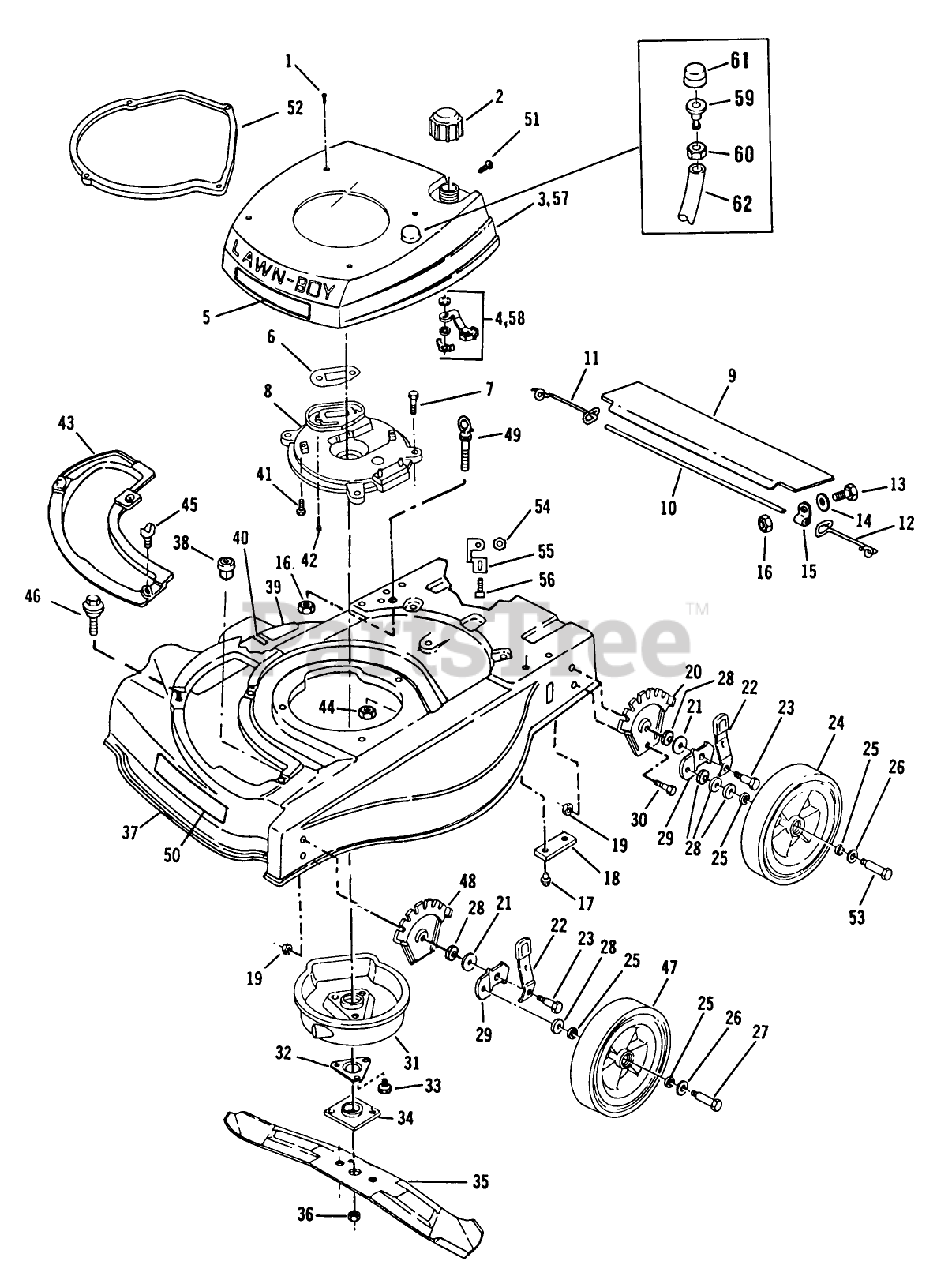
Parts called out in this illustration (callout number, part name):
1	SCREW LAWRENCE
2	FUEL CAP & INSERT
7	SCREW-HH
8	PLATE,MUFFLER F
10	ROD T/SHIELD ADV WIRE
11	SPRING;TRAILING SHIELD RH
12	SPRIG T/SHLD ASOC
14	Washer-Trailing Shield
15	CLAMP ROD KMC
16	LOCKNUT E
17	SCREW
19	LOCKNUT
21	WASHER
22	KNOB&SPRING FORMCO
23	BOLT
25	WASHER
26	SPACER
27	BOLT WHEEL
28	WASHER WROUGHT
32	SUPPORT F
33	SCREW
34	PLATE AND COLLAR ASM
36	NUT-BLADE
42	SCREW V
44	NUT-LOCK F
45	WING SCREW LAWRE
47	WHEEL & TIRE KIT
48	PLATE HGT ADJ TRO
49	BOLT-EYE
51	SCREW S
54	LOCKNUT E
60	LOCKNUT S
61	P-BULB LAV-RUB
62	TUBING-PRIMER POLY
